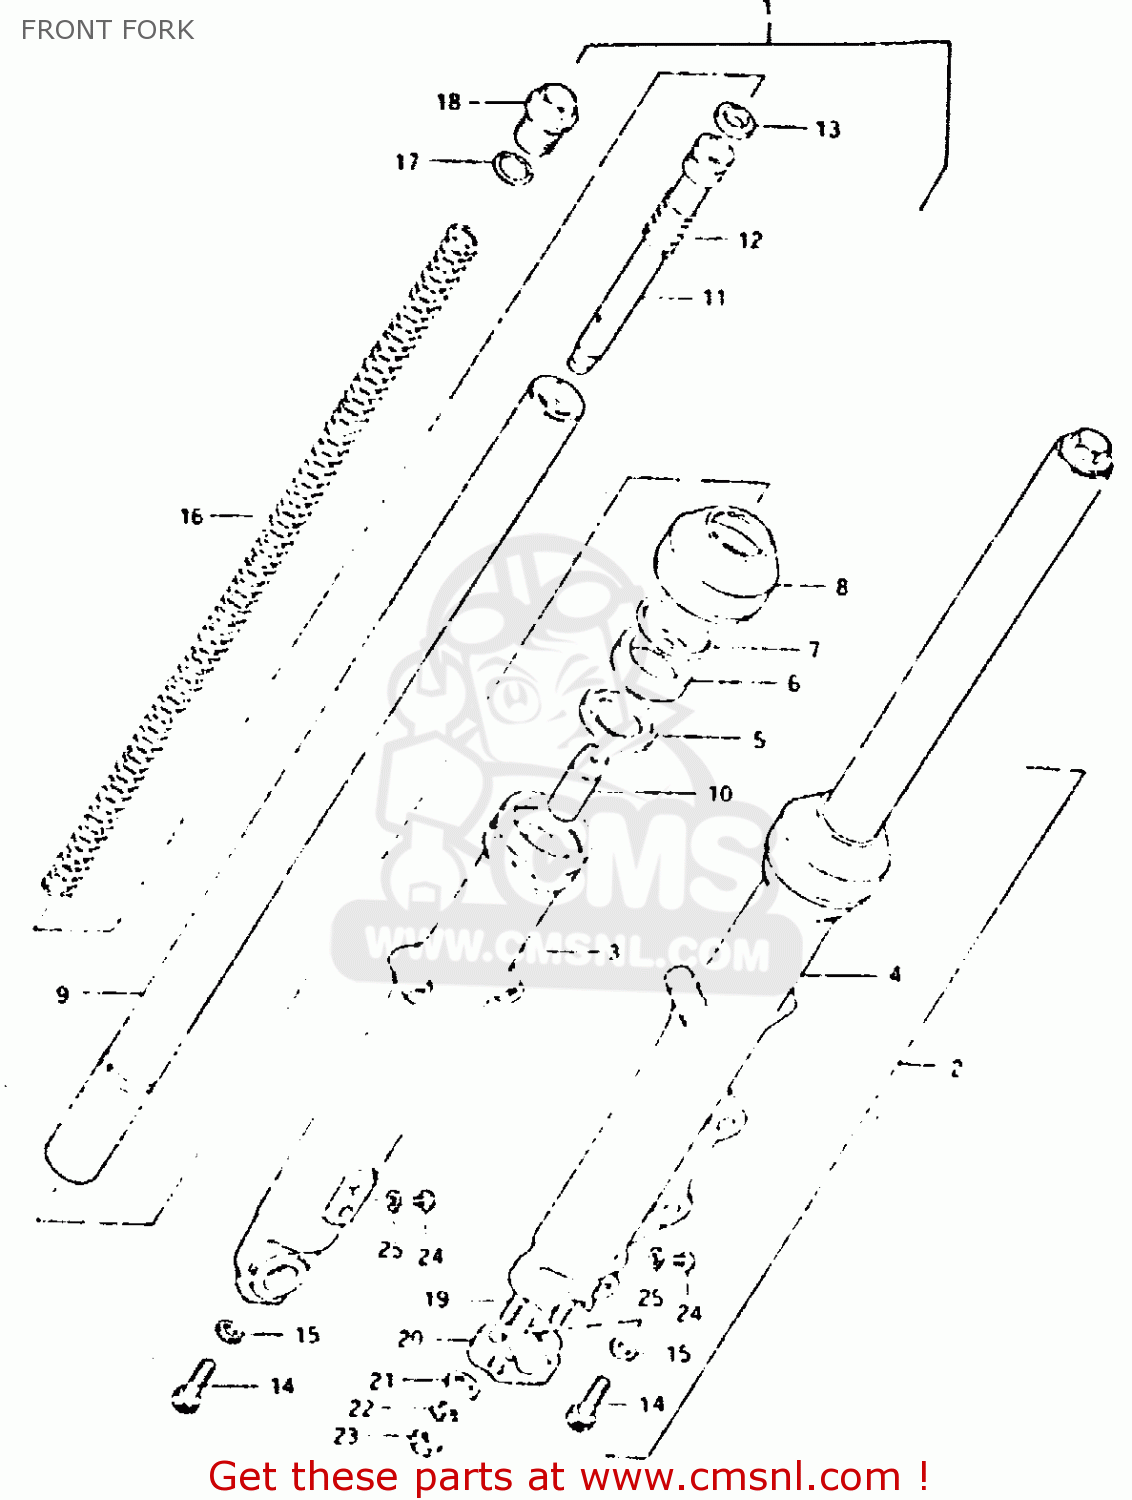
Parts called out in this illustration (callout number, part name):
1	DAMPER ASSEMBLY,RIGHT
2	DAMPER ASSEMBLY,LEFT
3	TUBE,FORK,OUTER,RIGHT
4	TUBE,FORK,LEFT,OUTER
5	SPACER,OIL SEAL
6	OIL SEAL,FRONT FORK
7	CIRCLIP,FORK OIL SEAL
8	DUST SEAL
9	TUBE,INNER
10	PIECE,OIL LOCK
11	CYLINDER,FRONT FORK
12	SPRING,REBOUND
13	RING,PISTON
14	BOLT(8X27)
15	GASKET (NAS)
16	SPRING
17	O RING
18	BOLT
19	STUD 8X25
20	HOLDER,AXLE
21	WASHER
22	LOCK WASHER
23	NUT (8MM)
24	SCREW 4X6
25	GASKET (NAS)
